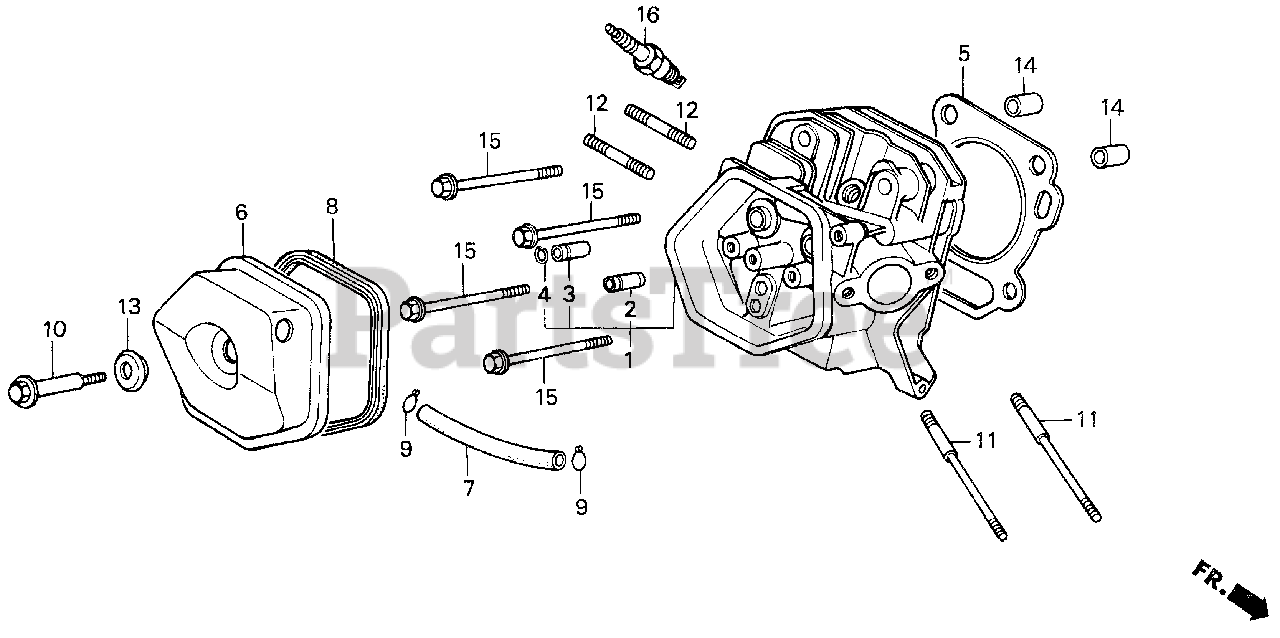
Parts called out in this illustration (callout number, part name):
1	CYLINDER HEAD
2	GUIDE, VALVE (OS)
3	GUIDE, EX. VALVE (OS)
4	CLIP, VALVE GUIDE
5	GASKET, CYLINDER HEAD
6	COVER, HEAD
7	TUBE, BREATHER
8	GASKET, CYLINDER HEAD COVER
9	CLIP, BREATHER TUBE
10	BOLT, HEAD COVER
11	BOLT, STUD (8X131.5)
12	BOLT, STUD
12	BOLT 2, STUD (8X32)
13	WASHER, HEAD COVER
14	PIN A, DOWEL (12X20)
15	BOLT, FLANGE (10X80)
16	SPARK PLUG (BPR5ES) (NGK)
16	SPARK PLUG (W16EPR-U) (DENSO)
16	SPARK PLUG (BPR6ES) (NGK)
16	SPARK PLUG (W20EPR-U) (DENSO)
